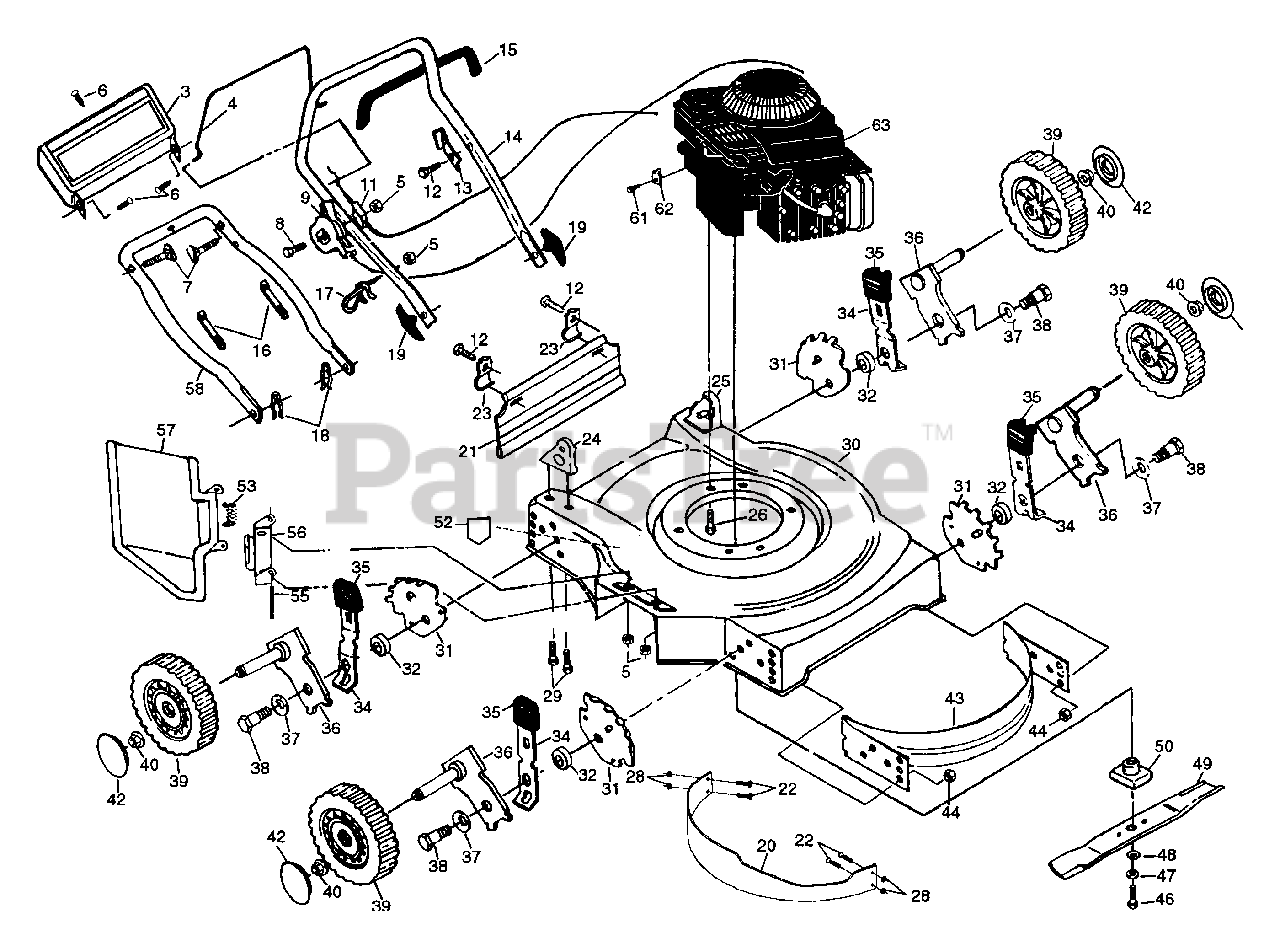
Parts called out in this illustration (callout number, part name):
3	Trim Plate
4	Control Bar
5	Locknut 1/4-20
6	Snap-in Fastener
7	Handle Bolt 5/16-18 x 1-3/4
8	Hex Washer Head Screw 1/4-20 x 2.12
9	Throttle Control
11	Engine Zone Control Cable
12	Hex Washer Head Screw #10-2
13	Up-Stop Bracket
14	Upper Handle
15	Handle Grip
16	Wire Tie
17	Rope Guide
18	Hairpin Cotter
19	Handle Knob
20	Closeout Plate
21	Rear Skirt
22	Machine Screw
23	Rear Skirt Bracket
24	Handle Bracket Assembly (Right)
25	Handle Bracket Assembly (Left)
26	Thread Rolling Screw 3/8-16 x 1
29	Screw 5/16-18
30	Lawn Mower Housing
31	Wheel Adjusting Bracket
32	Spacer
34	Selector Spring
35	Selector Knob
36	Axle Arm Assembly
37	Belleville Washer
38	Shoulder Bolt 3/8-16
39	Wheel Assembly
40	Flanged Locknut
43	Front Baffle
46	Hex Head Screw 3/8-24 x 1-3/8 Gr. 8
47	Helical Lockwasher 3/8
48	Hardened Washer
50	Blade Adapter
52	Danger Decal
53	Torsion Spring
56	Housing Bracket
57	Discharge Guard
58	Lower Handle
61	Thread Rolling Screw #10-32 x 5/8
62	Cable Clamp
63	Engine - Briggs
